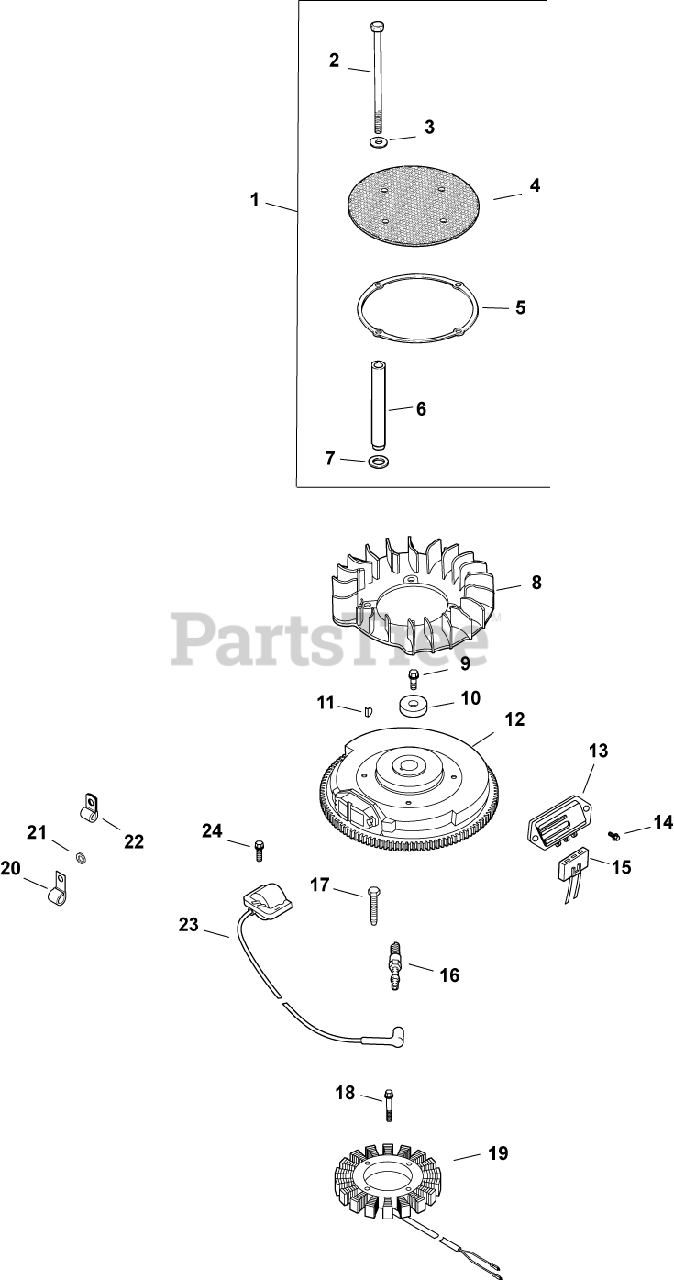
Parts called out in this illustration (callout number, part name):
1	KIT, CHOPPER SCREEN
2	SCREW, CAP M6X1.0X99.5
3	WASHER, FLAT 1/4" (O.D. 5/8")
4	SCREEN, GRASS
5	RING, SUPPORT USE 25 141 08-S
7	WASHER, SPRING 10 MM
9	SCREW, FLG M10X1.5X45 - (#25086361S)
10	WASHER, FLAT 13/32"
11	KEY, 3/16" X 5/8"
12	FLYWHEEL, PAINTED-USE 24 025 59-S
13	REG/RECT-15 AMP (KM)-USE 41 403 10-S
14	SCREW, PHL HD #11-16X7/8"
15	CONNECTOR, BODY (KM)-USE 25 155 41-S
16	PLUG, SPARK (STD)
17	SCREW, M5X0.8X25 - (#25086402S)
18	SCREW, SKT SET #10-24X1/4"
19	KIT, 15 / 20 AMP STATOR
20	CLIP, CABLE
21	WASHER, FLAT 1/4" (O.D. 1/2")
22	CLIP, TUBE & WIRING (KM)
23	KIT, MODULE IGNTN (CDI FIXED)
24	SCREW, FLG THD FRM M5X.8X20-(#25086399S)
